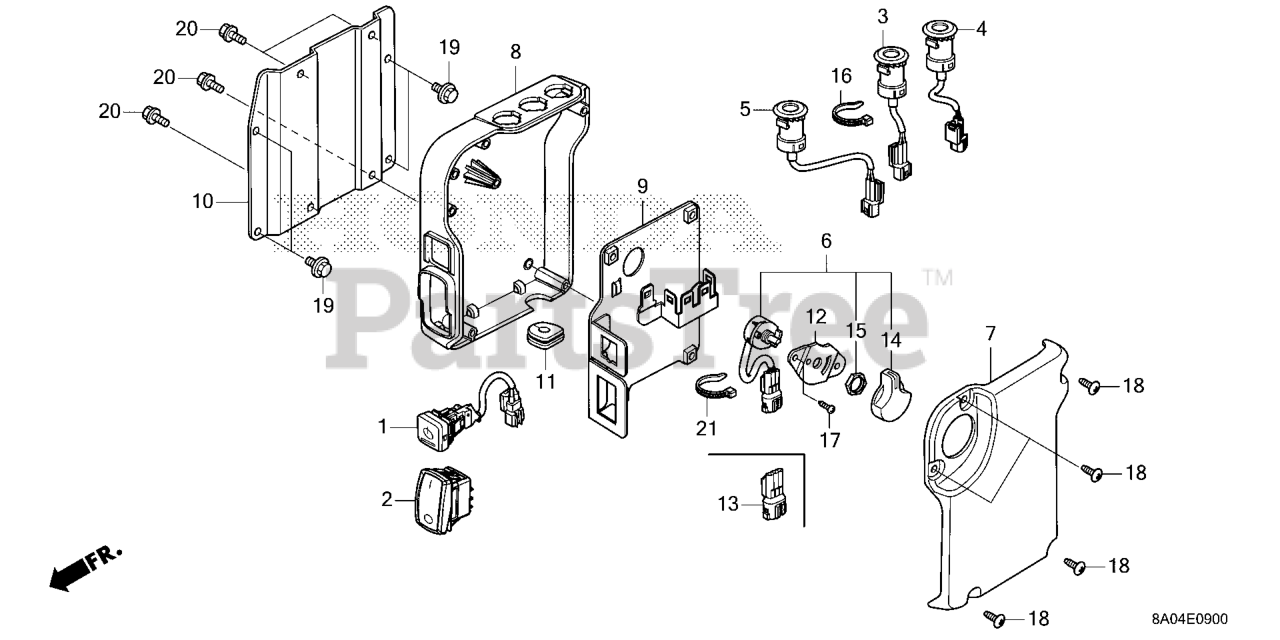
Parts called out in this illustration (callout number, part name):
1	SWITCH ASSY., POWER
2	SWITCH ASSY., START
3	LAMP, INDICATOR
4	LAMP, INDICATOR
5	LAMP, INDICATOR
6	VOLUME ASSY., SPEED
7	COVER, CONTL *NH1*
8	CASE, CONTL *NH1*
9	BRACKET, CONTL BOX
10	BRKT, CASE MTG *NH1*
11	GROMMET, CONTL BOX
12	BRKT, SPEED VOLUME
16	BAND (BLACK 3.5X140)
17	SCREW, TAPPING (5X14) (PO)
18	SCREW, TAPPING (5X16) (PO)
19	BOLT, FLANGE (6X10)
20	BOLT, FLANGE (6X14)
21	BAND (BLACK 3.5X140)
